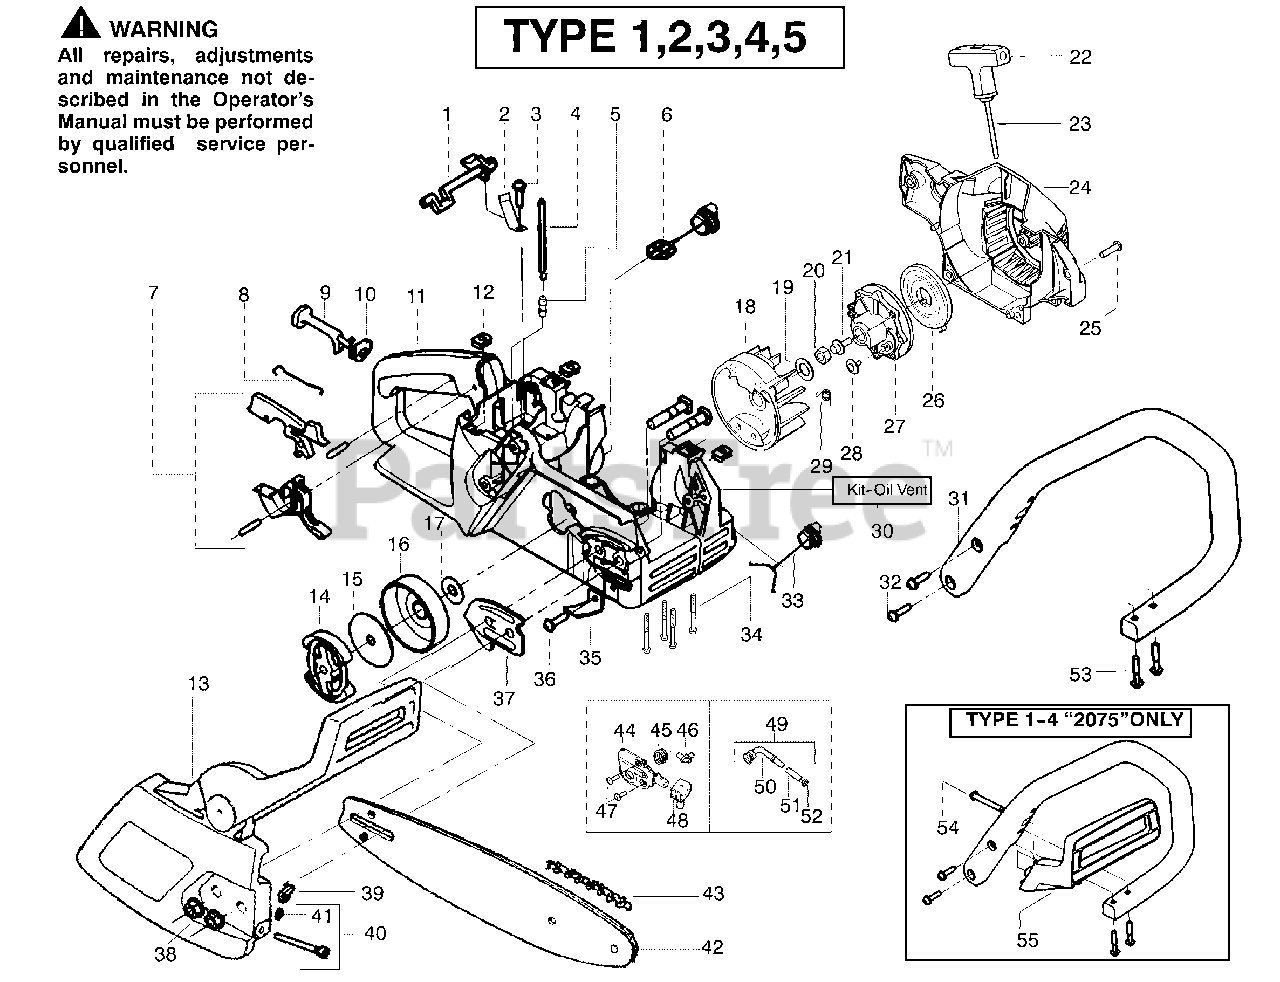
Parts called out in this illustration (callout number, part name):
1	Lever-Switch
2	Spring-Switch
4	Kit-Fuel Line (Large)
5	Fitting-fuel line
6	Assy-Fuel Cap
7	Kit-Trigger & Lockout
8	Wire-Throttle
9	Lever-Choke
10	Grommet-Choke Knob
11	Assy-Chassis 2075
12	Nut-Speed
13	Assy-Chainbrake 2075
14	Assy. - Clutch
15	Washer-Clutch
16	Assy-Drum W/brg.
17	Washer - Thrust
18	Assy-Flywheel
19	Washer-Flywheel
20	Nut-Flywheel
22	Handle-Starter
23	Kit-Rope
24	Housing-Fan 2075
26	Spring-Starter
27	Pulley-Starter
29	Spring-starter dog
30	Kit-Oil Vent
31	Handle-Front
33	Assy-Oil Cap
35	Chain Catcher
37	Plate-Bar Mounting
38	Nut-Bar Mounting
39	Pin-Bar Adjust
40	Kit-Bar Adj.
41	Retainer-Bar Adjust
42	Bar-14" 2075
43	Chain-14"
44	Kit-Oil Pump
45	Gear-Worm Spring
46	Elbow-Oil Pickup
48	Block-Seal
49	Assy-Oil-Pickup
50	Pickup-Oiler
51	Filter-Oil
52	Plug-Oil Filter
54	Bolt-Handguard
55	Handguard
